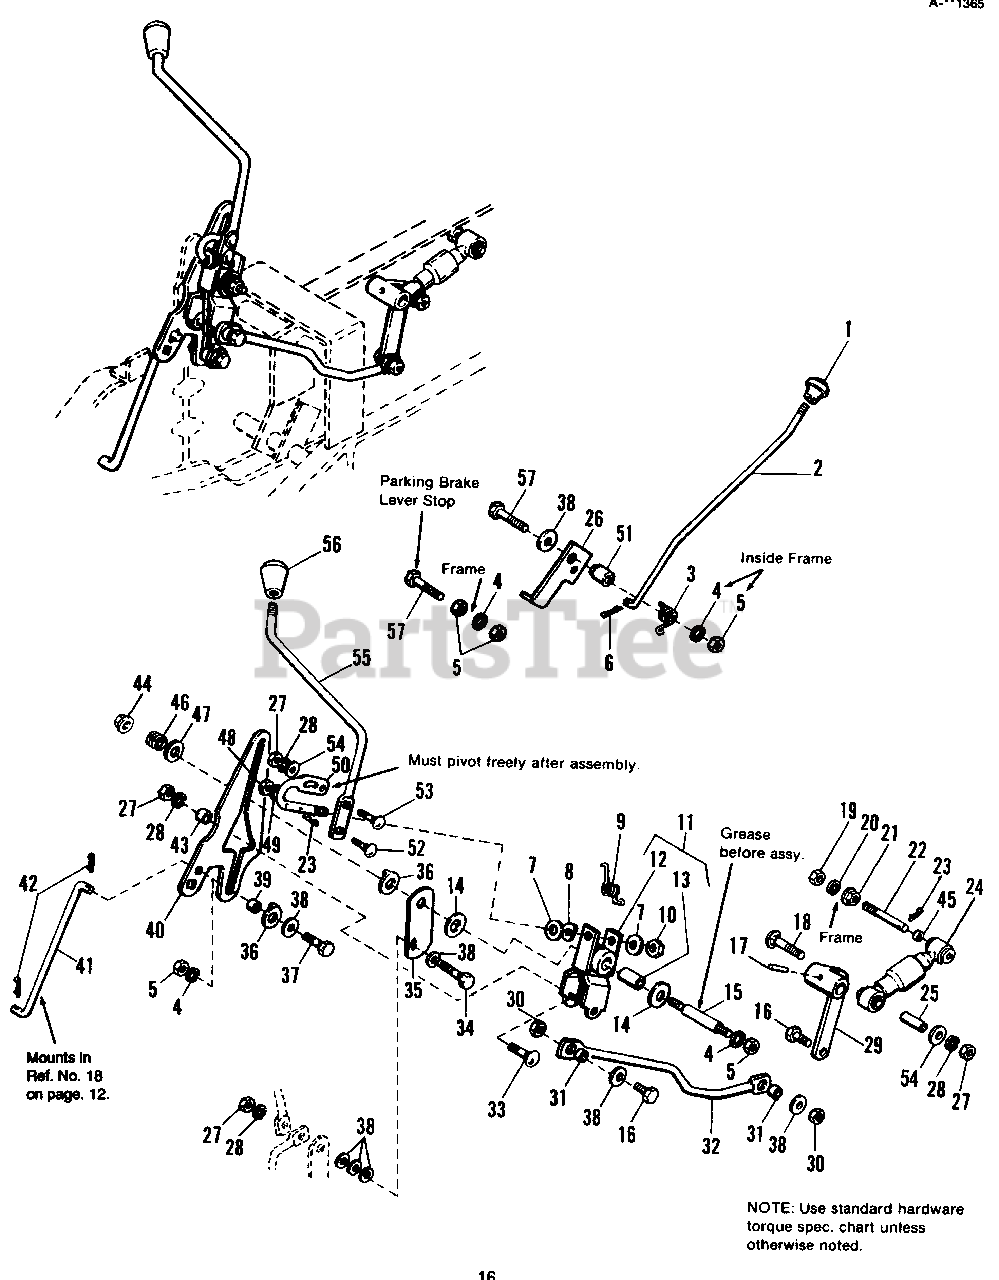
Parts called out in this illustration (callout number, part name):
1	KNOB, Parking Brake
2	ROD, Parking Brake
3	SPRING, Torsion
4	LOCKWASHER, 3/8
5	NUT, Hex, 3/8-16
6	PIN, Cotter, 1/16 x 3/4
7	WASHER, Plain, 1/2 x 1-1/4 x 5/64
8	WASHER, Curved, 1/2 x 1 x 1/64
9	SPRING, Torsion
10	NUT, Hex, Centerlock, Jam, 1/2-13
11	LEVER ASSY., Hyd. Control (Incl. Ref. Nos. 12 & 13)
12	LEVER ASSY., Hyd. Control
13	BEARING SLEEVE
14	DISC., Friction
15	SHAFT, Pivot
16	CAPSCREW, Hex Hd., 3/8-16 x 7/8
17	PIN, Spring, 1/4x 1-1/4
18	BOLT, Carriage, 5/16-18 x 1-3/4
19	NUT, Hex, 7/16-14
20	LOCKWASHER, 7/16
21	NUT, Hex, Flange, Whizlock, 7/16-14
23	PIN, Cotter, 1/8 x 3/4
24	SHOCK ABSORBER (Speed Control)
26	LEVER, Parking Brake
27	NUT, Hex, 5/16
28	LOCKWASHER, 5/16
29	LEVER ASSY., Control
30	NUT, Hex, Centerlock, 3/8-16
31	SPACER, Ratchet Cage
32	ROD, Hydro Control
33	BOLT, Carriage, 5/16-18 x 1-1/4
34	CAPSCREW, Hex Hd., 5/16-18 x 1-3/4
35	BRACE, Hydro. Control
36	WASHER, Lug
37	CAPSCREW, Hex Hd., 3/8-16 x 1-1/4
38	WASHER, Plain, 13/32 x 7/8 x 5/64
39	SPACER, 25/64 x 5/8 x 13/32
40	CAM PLATE, Hydro. Lever
41	ROD, Ground Speed Control
42	PIN, Cotter, 3/32 x 3/4
44	NUT, Hex Flange Lock, 3/8-16
46	SPRING, Compression
47	WASHER, Plain, 21/32 I.D.
48	NUT, Hex, 1/4-20
49	LOCKWASHER, 1/4
50	ROD HYDRO., Control
51	SPACER, Parking Brake
52	BOLT, Carriage, 1/4-20 x 1-1/4
53	BOLT, Carriage, 5/16-18 x 1
54	WASHER, Plain, 11/32 x 3/4 x 1/16
55	LEVER, Speed Control
56	KNOB, Speed Control
57	CAPSCREW, Hex Hd., 3/8-16 x 1-3/4
